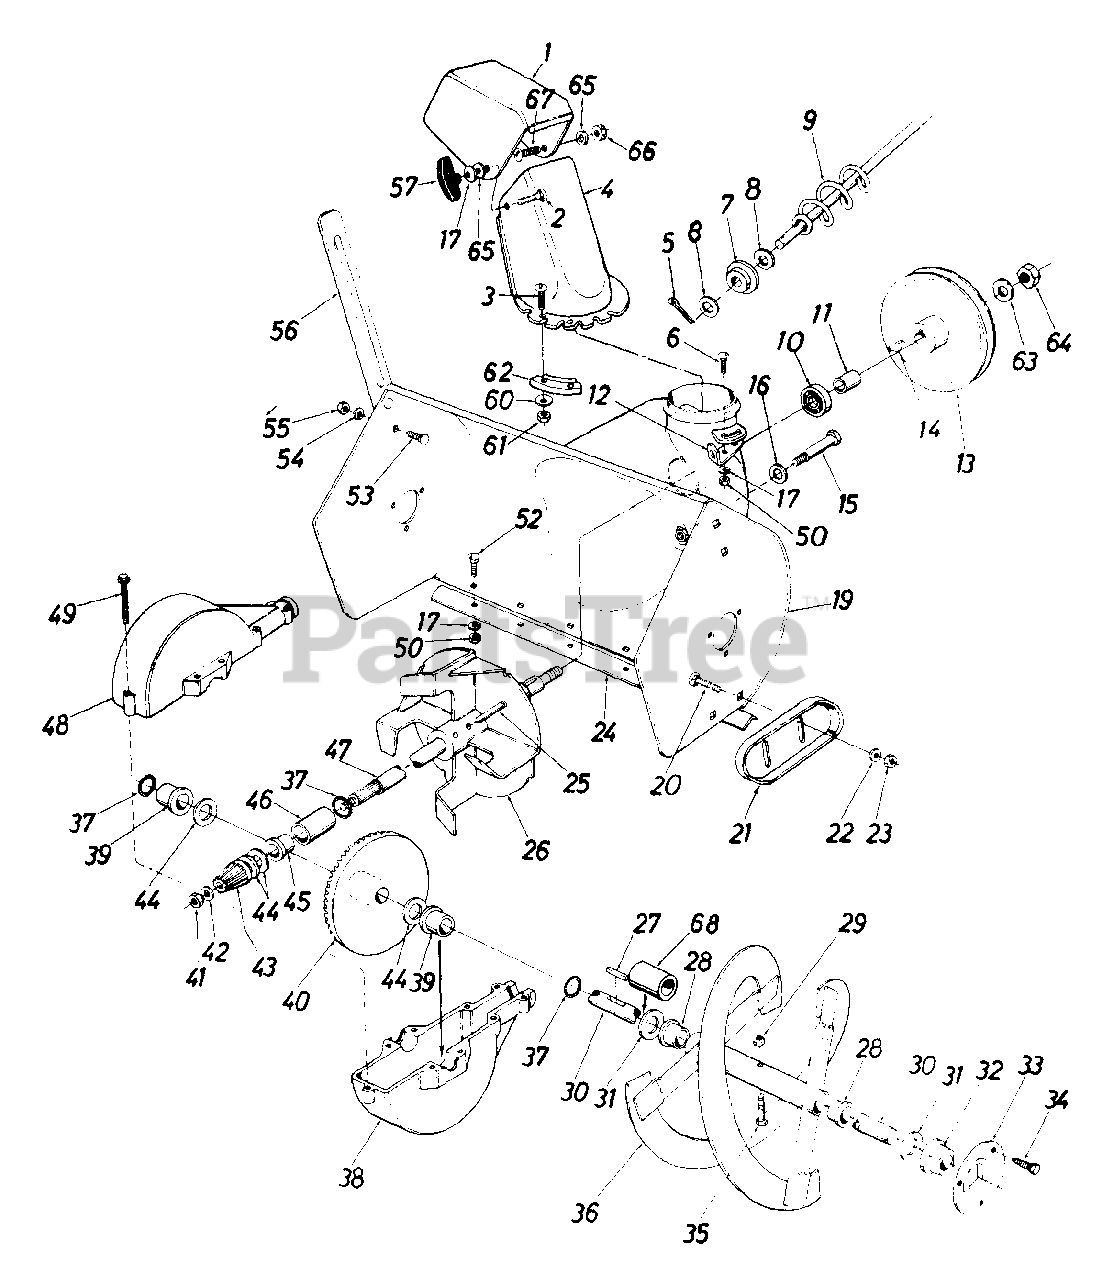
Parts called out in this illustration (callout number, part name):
1	Upper Chute
2	Carriage Bolt 5/16-18 x 1.0"
3	Truss Mach. Scr. 1/4-20 x .75"
4	Lower Chute
5	Cotter Pin
6	Carriage Bolt 5/16-18 x .75"
7	Bushing
8	Fl-Wash. .385 I.D. x .62" O.D.
9	Chute Crank Ass'y.
10	Ball Brg. .62" I.D. x 1.38" O.D.
11	Spacer .63" I.D. x .88" O.D. x .900" Lg.
12	Chute Crank Brkt.
13	1/2" "V"-Pulley .625" I.D. x 7.50" O.D.
13	5/8" "V"-Pulley .625" I.D. x 7.50" O.D.
14	#61 Hi-Pro Key 3/16" x 5/8" Dia.
15	Shld. Bolt .50" Dia. x 2.11"
16	Bell-Wash. .40" I.D. x .88" O.D. x .06
17	Bell-Wash. .34" I.D. x .88" O.D.
19	26" Blower Housing Ass'y.
20	Carriage Bolt 3/8-16 x .62"
21	Slide Shoe
22	Bell-Wash. 3/8" I.D.
23	Hex Jam Nut 3/8-16 Thd.
24	20" Shave Plate
24	24" Shave Plate
24	26" Shave Plate
25	Spring Pin Spiral 1/4" Dia. x 1.50" Lg.
26	11" Dia. Blower Fan Ass'y.
27	Sq. Key 3/16" x 1.5" Lg.
28	Flange Brg. .75" I.D. x .88" O.D.
29	Hex Ins. L-Nut 5/16-18
30	Spiral Axle
31	Fl-Wash. .75" I.D. x 1.50" O.D. x .06
32	Flange Brg. w/Flats .755" I.D.
33	Bearing Housing
34	Hex Wash. Hd. Self-Tap Scr. 5/16-24 x .62" Lg.
35	Hex Bolt 5/16-18 x 1.50" Lg.
36	20" Spiral Ass'y. - L.H.
36	24" & 26" Spiral Ass'y. - L.H.
37	O-Ring - 3/4" I.D.
38	Bevel Gear Housing - Lower Half
39	Plastic Flange Brg. .755" I.D.
40	Bevel Gear
41	Hex Cent. L-Nut 5/16-24 Thd.
42	Fl-Wash. .34" I.D. x .62" O.D. x .06
43	Pinion Gear
44	Fl-Wash. .75" I.D. x 1.25" O.D. x .06
45	Flange Brg. .755" I.D.
46	Sleeve Brg. .755" I.D.
47	Blower Axle
48	Bevel Gear Housing - Upper Half
49	Hex Wash. Hd. Self-Tap Scr. 1/4-20 x 1.00" Lg.
50	Hex Nut 5/16-18 Thd.
52	Carriage Bolt 5/16-18 x .62" Lg.
53	Carriage Bolt 5/16-18 x .62" Lg.
54	L-Wash. 5/16" I.D.
55	Hex Nut 5/16-18 Thd.
56	Drift Cutter Bar
60	Fl-Wash. 1/4" I.D.
61	Hex L-Nut 1/4-20 Thd.
62	Chute Flange Keeper
63	Fl-Wash. .64" I.D. x .94" O.D. x .06
64	Hex Jam Nut 5/8-18 Thd.
65	Fl-Wash. .344 I.D. x 1.125 O.D.
66	Hex L-Nut 5/16-18 Thd.
67	Truss Mach. Scr. 5/16-18 x .75" Lg."
68	Spacer
